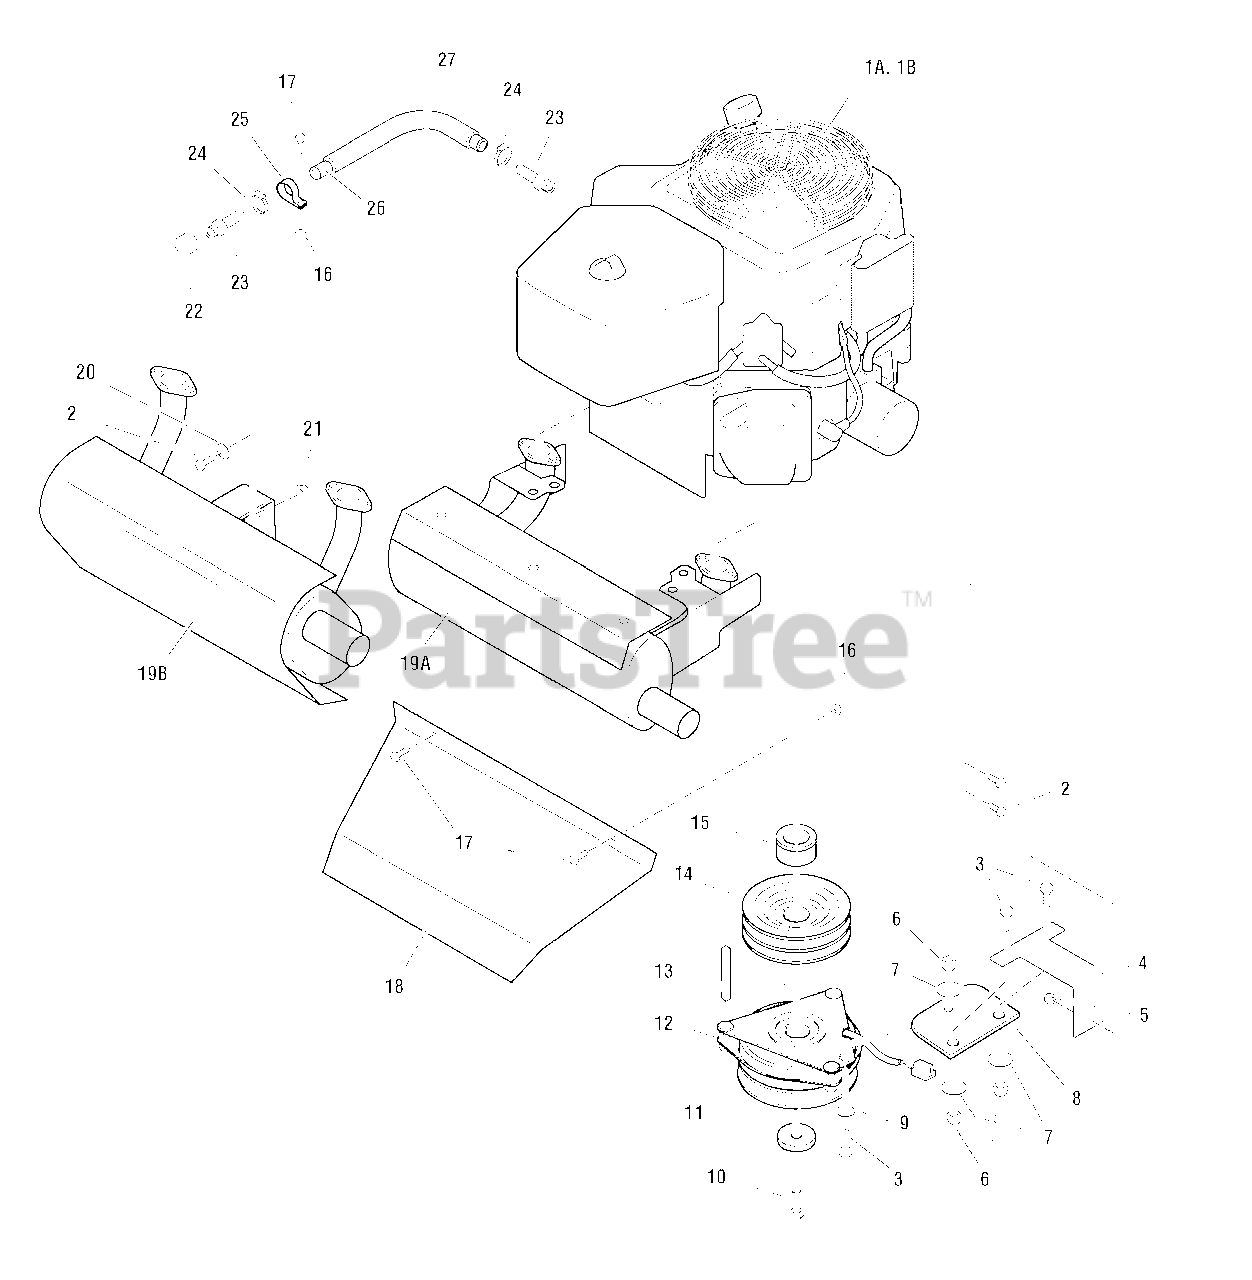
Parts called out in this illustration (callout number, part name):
1A	ENGINE, 21HP Kohler
1B	ENGINE, 23HP Kohler
2	CAPSCREW, Hex Hd, 5/16-18 x 3/4
3	CAPSCREW, Hex Hd, 3/8-16 x 1
4	CLUTCH ANCHOR
5	NUT, Hex, Nylon Lock, 5/16-18
6	NUT, Hex, Nylon Lock, 3/8-16
7	WASHER, Fender, 3/8
8	CLUTCH ANCHOR PAD
9	WASHER, 3/8
10	CRANKSHAFT BOLT, 7/16 x 2
11	SPACER, .45 x 1.88 x .38
12	ELECTRIC CLUTCH
13	KEY, 1/4 Sq. x 3-1/2
14	CRANKSHAFT PULLEY
15	SPACER, 1.13 x 1.75 x 1.03
16	NUT, Hex, Serrated Flange, 1/4-20
17	CAPSCREW, Hex Hd, 1/4-20 x 3/4
18	MUFFLER HEAT SHIELD (for use with silver version muffler only)
19A	** MUFFLER (silver version, S/N 101-123, both models)
19B	MUFFLER (black version, S/N 124 & up, both models)
20	WASHER, 5/16
21	NUT, Hex, Serrated Flange, 5/16-18
22	CAP, 3/8NPT
23	FITTING, 3/8NPT - 1/2 Str.
25	CLAMP, Vinyl
27	WIRE LOOM, 12"
